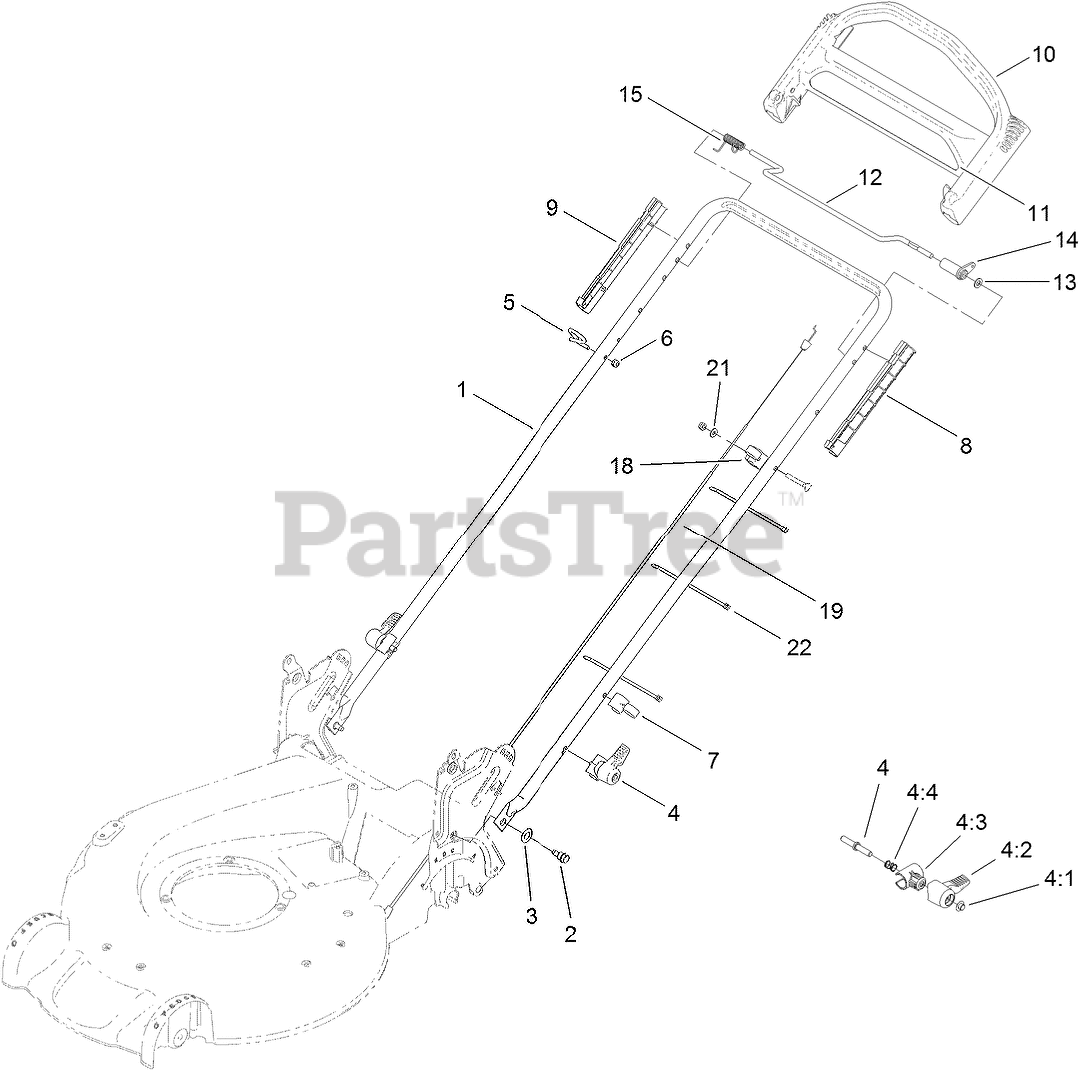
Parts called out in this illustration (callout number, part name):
1	HANDLE
2	BOLT-SHOULDER
3	WASHER-SPRING, CONICAL
4	QUICK RELEASE ASM
4:1	NUT-PUSH
4:2	LEVER
4:3	ANCHOR-SPRING
4:4	SPRING-COMPRESSION
5	GUIDE-ROPE
6	NUT-LOCK, NI
7	GUIDE-CABLE
8	GUIDE-LH
9	GUIDE-RH
10	HANDLE-CONTROL
12	BAR-CONTROL, TRACTION
13	WASHER-PLAIN
14	LEVER-TRACTION
15	Spring-Torsion
18	ANCHOR-CABLE
19	CABLE-TRACTION
21	WASHER-FLAT
22	TIE-CABLE
